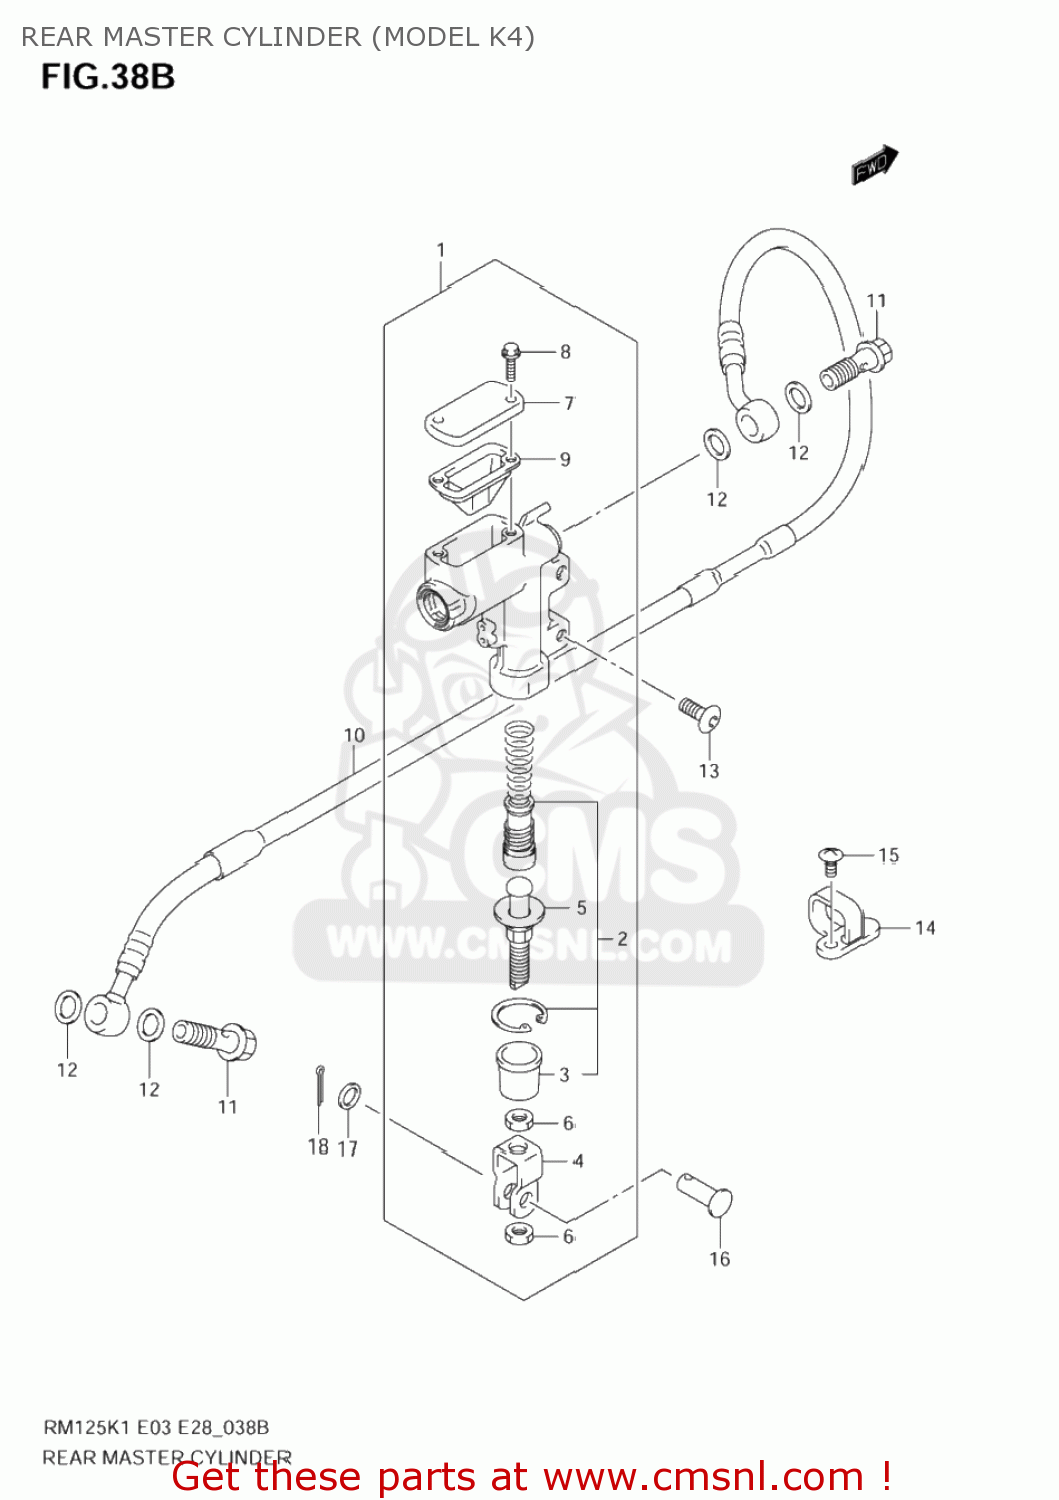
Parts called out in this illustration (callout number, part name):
1	CYLINDER SET,R
2	PISTON/CUP SET
3	BOOT
4	YOKE
5	ROD,PUSH
6	NUT
7	CAP
8	SCREW
9	DIAPHRAGM
10	HOSE,RR BRAKE
11	BOLT UNION
12	WASHER(10X15X1.5)
13	SCREW(6X16)
14	GUIDE,RR BRAKE
15	SCREW
16	PIN(8X20)
17	WASHER (8.5X14X1.6)
18	PIN
